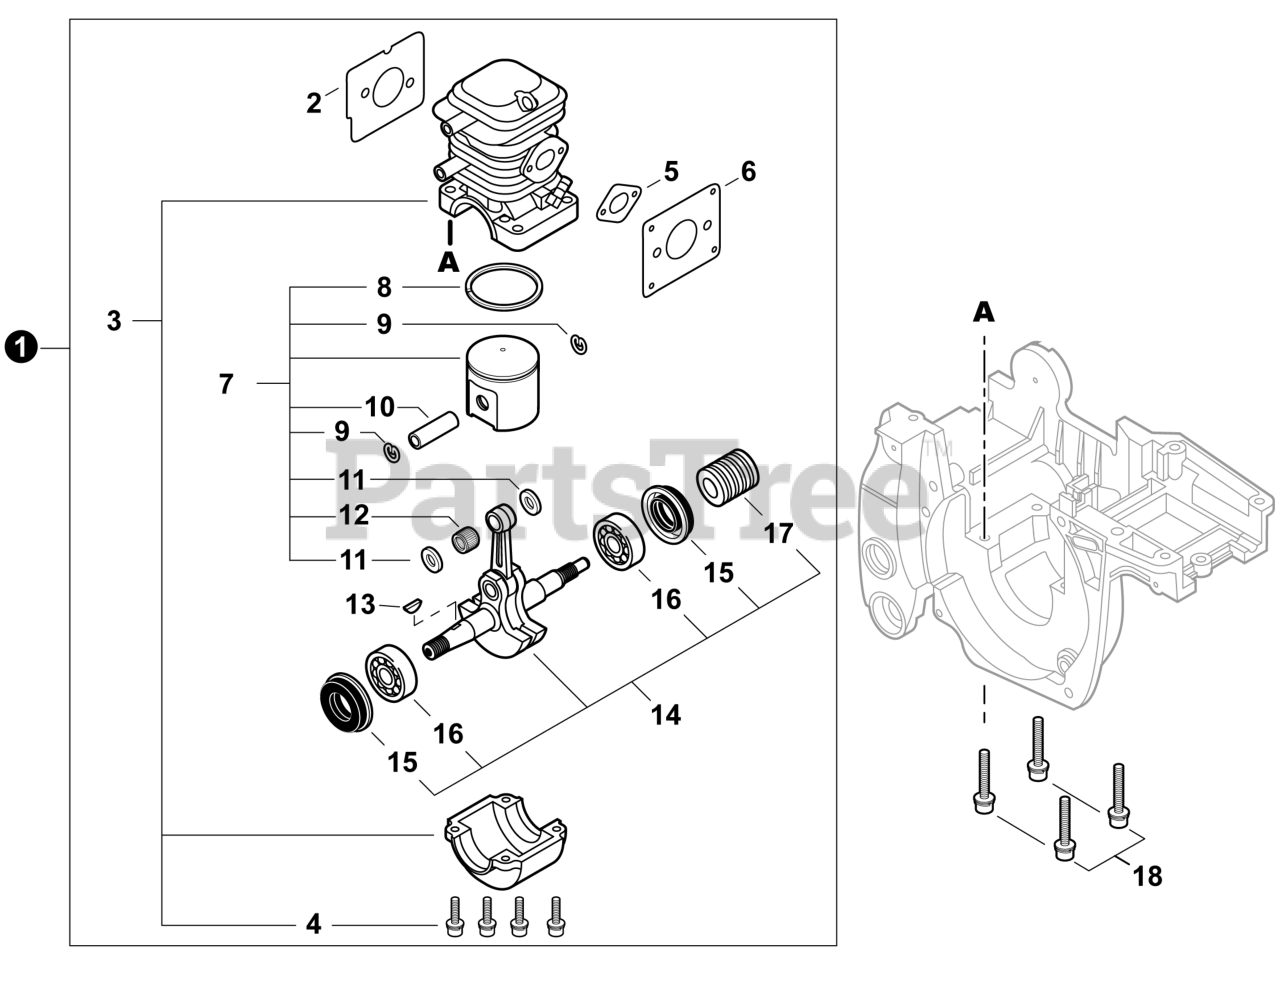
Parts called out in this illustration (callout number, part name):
1	SHORT BLOCK
2	GASKET, EXHAUST
3	CRANKCASE KIT
4	BOLT 5×22
5	GASKET, INTAKE
6	GASKET, INTAKE
7	PISTON KIT
8	RING, PISTON
9	RING, SNAP
10	PIN, PISTON
11	WASHER, THRUST
12	BEARING, NEEDLE 9
13	KEY, WOODRUFF
14	CRANKSHAFT ASSY
15	SEAL, OIL 12
16	BEARING, BALL 6201
17	GEAR, WORM
18	BOLT 5×30
